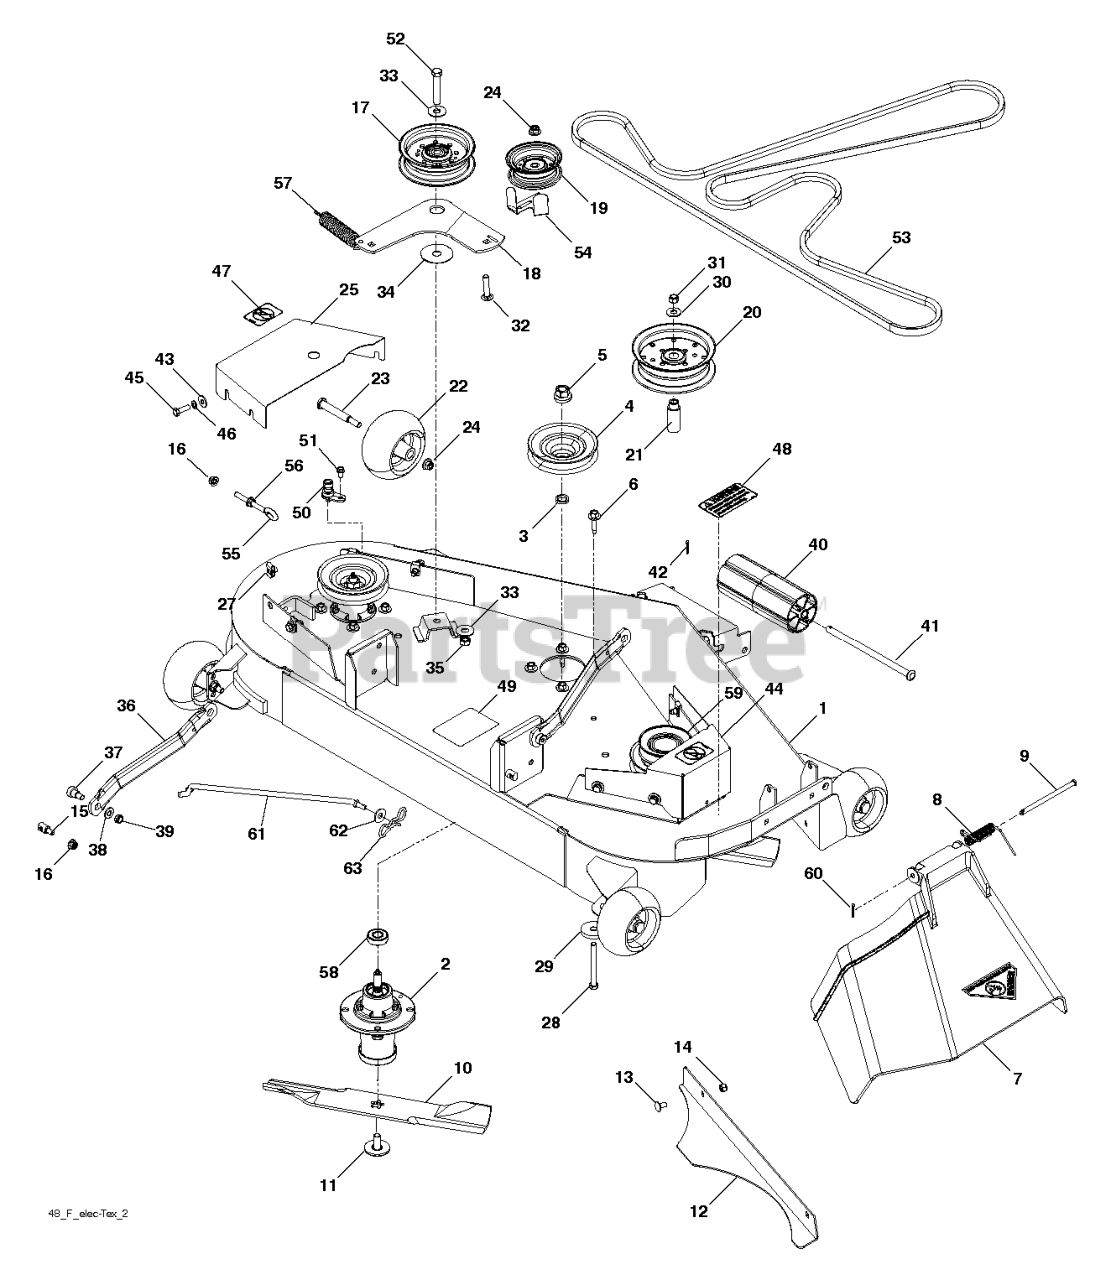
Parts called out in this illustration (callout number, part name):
1	Decks
2	MANDREL.DECK.ASSEMBLY
3	WASHER-SPACER
4	PULLEY.DRIVEN.DECK.48'
5	LOCKNUT - 9/16
6	WASHER HEAD SCREW
7	DISCHARGE CHUTE 48"
8	SPRING - TORSION
9	PIN-CLEVIS 5/16 DIA X 5.19 ZD
10	BLADE, 16-1/4"
11	BLADE BOLT ASSY-7/16" TB REPL
12	CONFINEMENT PLATE 48" BLK
13	CARRIAGE BOLT 5/16C X 5/8"
14	NUT 5/16 NYLOC
15	STUD.FASTNER.W/ANTI-ROTATE
16	5/16-18 NYLOC FLANGE NUT
17	PULLEY.IDLER.MWR.STATI.LH
18	ARM, IDLER, BLK
19	PULLEY.IDLER.FLAT
20	PULLEY, IDLER
21	BUSHING, IDLER
22	GAUGE WHEEL
23	SHOULDER BOLT 1/2X2-5/8 ZD SPE
24	NUT 3/8-16 HEX FLG NYLOC ZD
25	SHIELD.BELT.LH.ORANGE
27	U-CLIP 5/16-18 NUT RETAINER
28	HCS 3/8-16 X 3-1/2 GR5 ZD
29	SPINDLE WASHER
30	WASHER 3/8 FLAT
31	NUT 3/8-16 NYLOC
32	RHSNB 3/8-16X1-3/4
33	WASHER 7/16 FLAT ZD
35	7/16-14 HEX NUT W/NYL RING ZD
36	ARM.SUSPENSION.MOWER
37	SB 3/8-16 X 3/8 SKT HD ZD
38	WASHER 3/8 SAE FLAT
39	NUT HEX 3/8-16 NYLON, THIN
40	NOSE ROLLER 48"
41	ROD.ROLLER.NOSE.NARROW.48"
42	PIN.COTTER.5/16.BOW TI
43	WASHER 5/16 FLAT
44	SHIELD, BELT, RH 48 ORG
45	HCS 5/16C X 1
46	WASHER.LOCK.HVY.HLCL.SPR.5/16
47	DECAL, NO STEP
48	DECAL, CAUTION
49	DECAL.MOWER.SCH.48/54
50	PORT.WASHOUT
51	BOLT 1/4-20 X 1/2 HWST
52	BOLT 7/16-14 X 2-1/2 GR 5 ZD
53	BELT, 135" EL
54	BELT GAURD
55	EYE BOLT 5/16 X 3.50
56	NUT 5/16C WHIZ
58	BEARING, BALL
59	RP PULLEY, COLLECTION 48
60	RETAINER CLIP
61	ROD.ANTI.SWAY.48/54"K4
62	WASHER
63	PIN.COTTER.5/16.BOW TI
